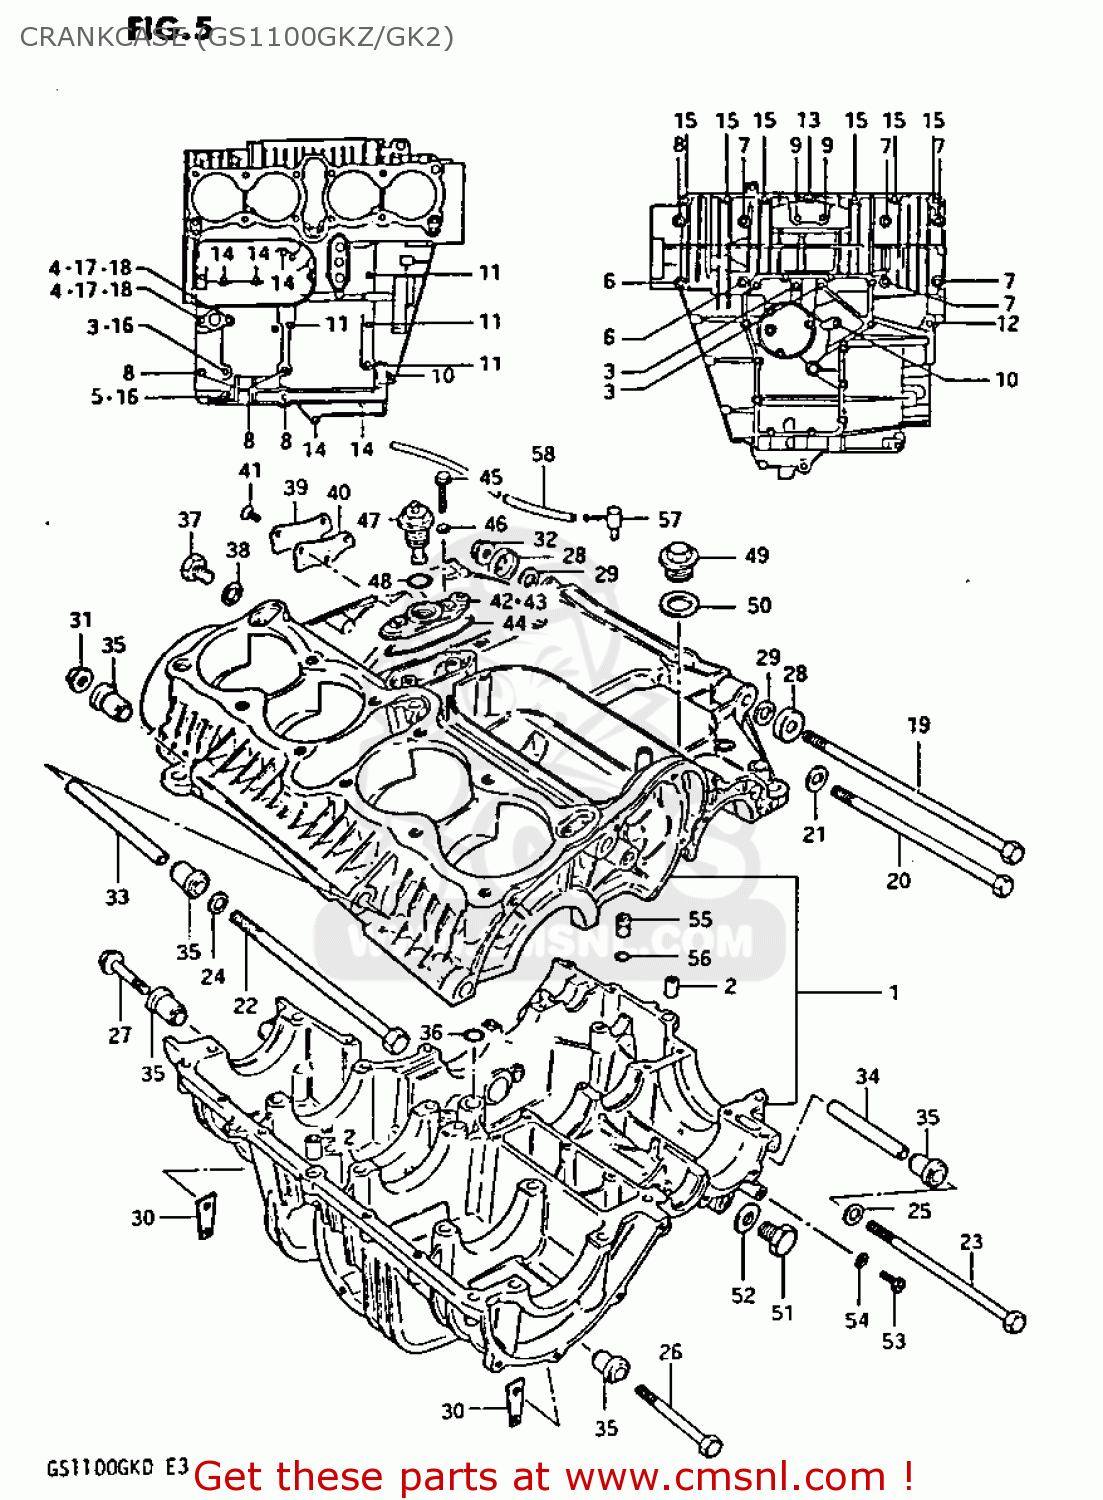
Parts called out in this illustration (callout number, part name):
1	CRANKCASE SET
2	PIN
3	BOLT(8X125)
4	BOLT
5	BOLT(8X105)
6	BOLT(8X100)
7	BOLT 8X90
8	BOLT 8X65
9	BOLT
10	BOLT (6X90)
11	BOLT (6X75)
12	BOLT
13	BOLT ,6X50
14	BOLT,UNDER
15	BOLT 6X35
16	NUT
17	NUT
18	GASKET 8.2X14X1 (NAS)
19	BOLT
20	BOLT
21	WASHER 10MM
22	BOLT 10X250
23	BOLT
24	WASHER
25	WASHER 10MM
26	BOLT
27	BOLT 10X55
28	WASHER
29	WASHER(10.5X20X3.2)
30	NUT
31	NUT
32	NUT 10MM
33	SPACER
34	SPACER
35	BUSH
36	O RING(D:3.2,ID:12.9)
37	PLUG(14X12)
38	GASKET(14X19.2X2) (NAS)
39	CAP,OIL GALLERY
40	GASKET,OIL GALLERY CAP (NAS)
41	SCREW
42	HOUSING,OIL PRESSURE SWITCH
43	HOUSING,OIL PRESSURE SWITCH
44	O RING,PRESSURE SWITCH HOUSING
45	BOLT 6X25
46	GASKET(5.8X13X1.2) (NAS)
47	SWITCH ASSEMBLY
48	O RING(D:1.9,ID:18.8)
49	PLUG
50	GASKET
51	PLUG
52	GASKET(14X19.2X2) (NAS)
53	SCREW(6X10)
54	GASKET(5.8X13X1.2) (NAS)
55	UNION
56	O RING(D:1.05,ID:3.1)
57	BPLUG,BEVEL GEAR BREATHER
58	HOSE
